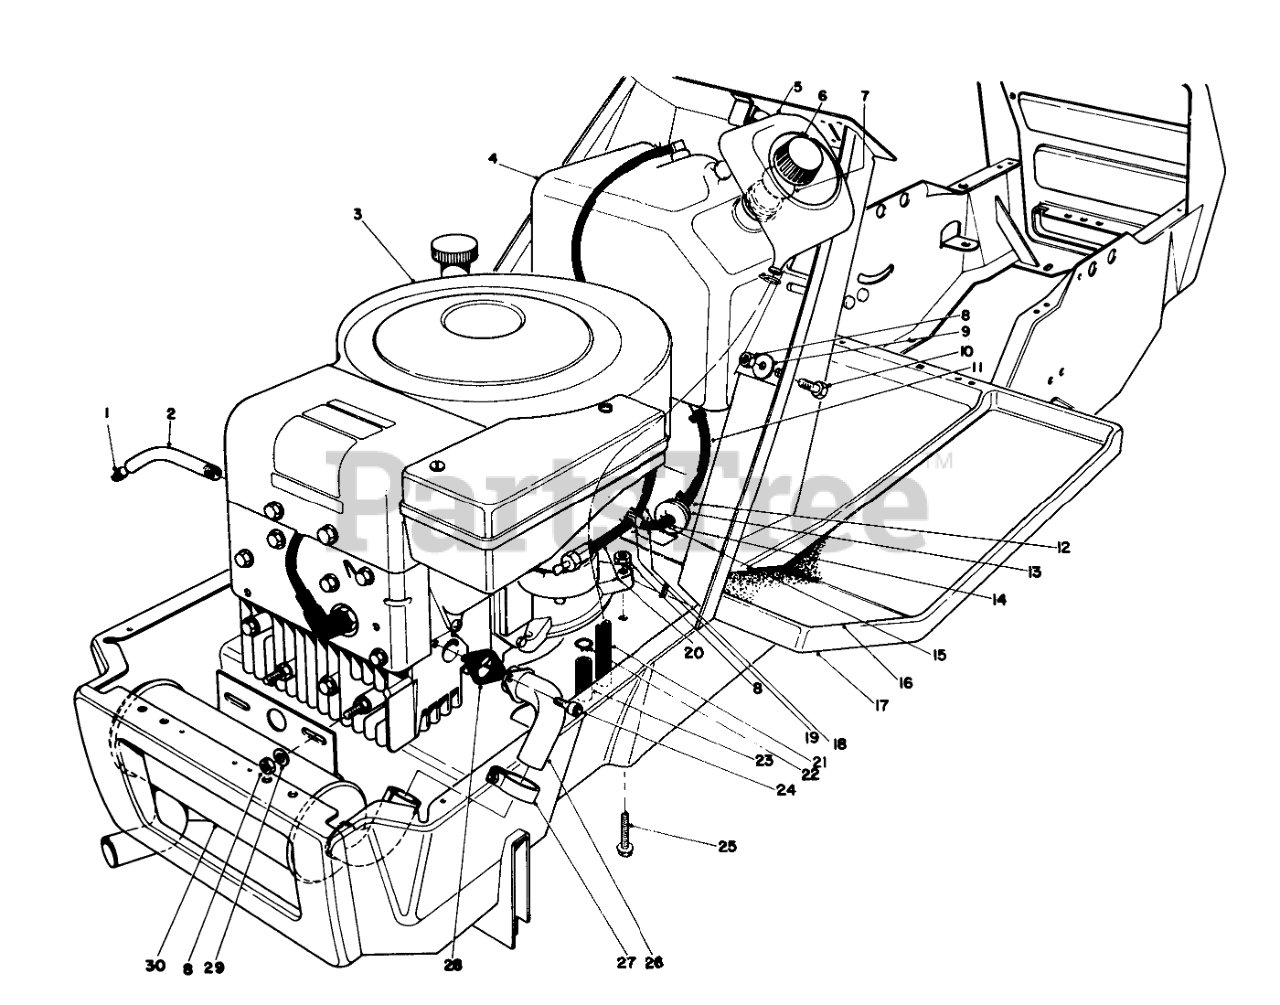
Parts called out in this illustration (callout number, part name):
1	PLUG-PIPE, SQH
2	OIL DRAIN TUBE
3	Engine
4	Gas Tank (Incl. Ref. #5)
5	Funnel Overflow
6	Gas Cap Assembly (Incl. Ref. #7)
7	Gasket Gas Cap
8	NUT-LOCK, CONE
9	WASHER
10	SCREW-HH
11	Gas Hose
12	CLAMP-HOSE
13	Nut
14	Clamp
15	Hose Gas Return
16	LH FOOT TREAD
17	Frame
18	Hose Gas
19	Fitting-Barbed Y
20	Hose Gas
21	FUNNEL HOSE
22	HOSE CLAMP
23	CARB DRAIN HOSE
24	SCREW-HSH
25	SCREW-HH
26	10 HP EXHAUST PIPE WA
27	MUFFLER CLAMP
28	Gasket Exhaust
29	WASHER-PLAIN
30	EXHAUST MUFFLER 10 HP
